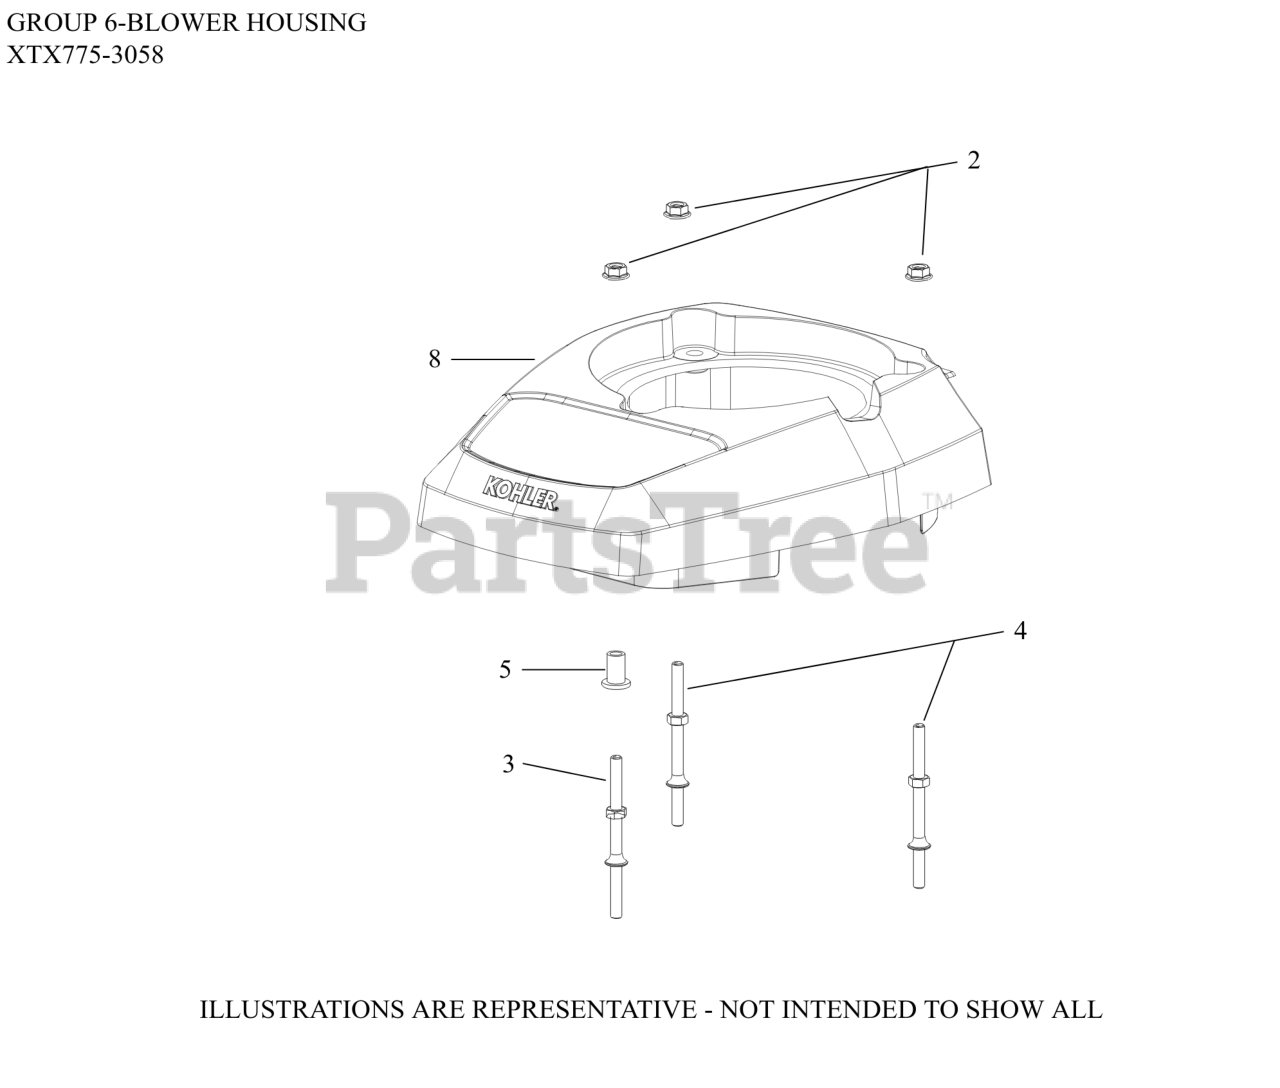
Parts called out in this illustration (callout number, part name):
2	NUT, HEX FLANGE (M6) - USE 14 100 16-S
3	STUD-USE 14 072 25-S
4	STUD-USE 14 072 26-S
8	COVER, ENGINE
